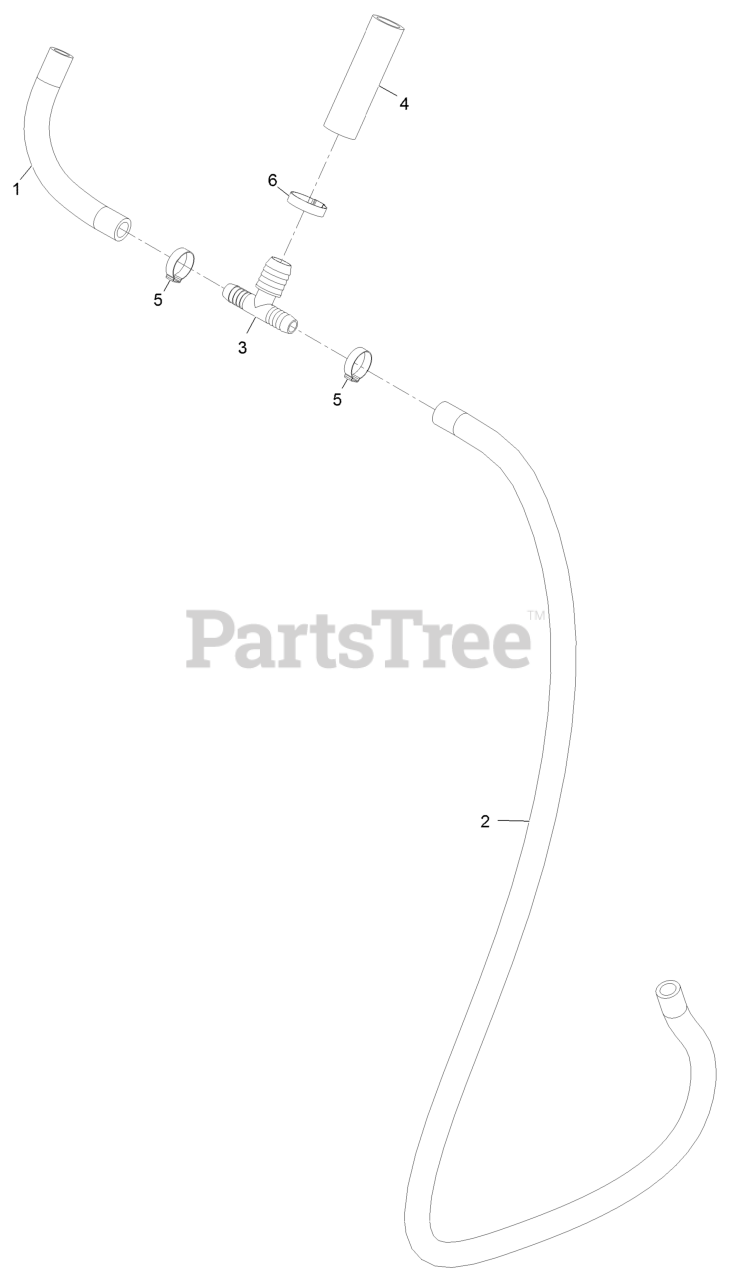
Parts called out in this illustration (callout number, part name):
1	HOSE-WATER
2	HOSE-WATER
3	FITTING-TEE
4	HOSE-WATER
